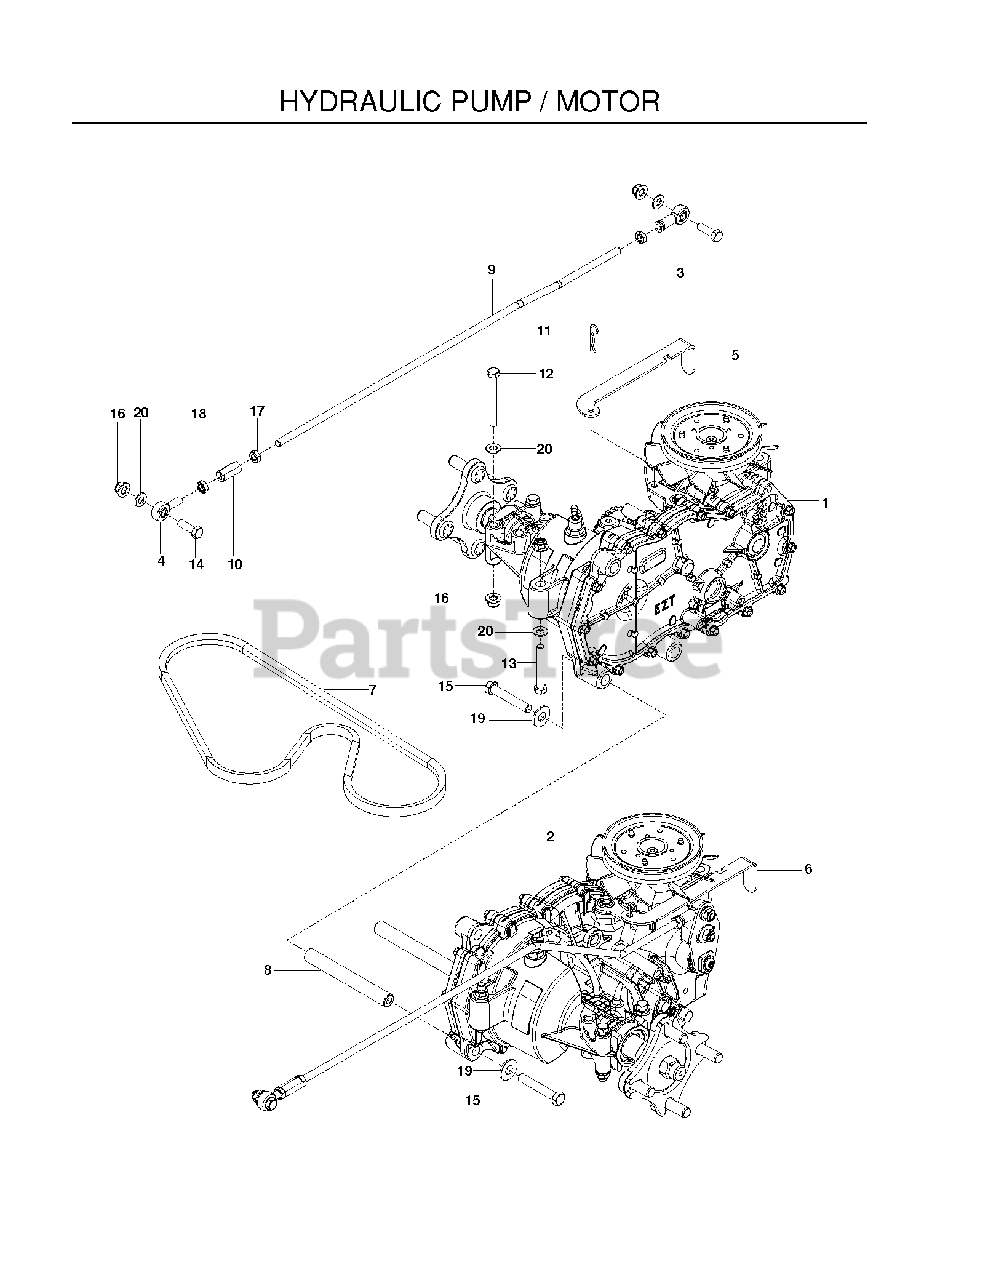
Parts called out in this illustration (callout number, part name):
1	HG_HYDRO RH
2	HG_HYDRO LH
3	RH ROD END
4	RB ROD.END.LH
5	RELEASE LEVER RH
6	RELEASE LEVER LH
7	BELT, EL 51.O4
8	SPACER, HYDRO
9	CONTROL ROD
10	ROD END COUPLER
11	HAIRPIN #2
12	HCS 5/16C X 2-3/4
14	HCS 5/16C X 1
15	HCS 3/8C X 2 1/4
16	5/16-18 NYLOC FLANGE NUT
17	NUT 5/16-24 UNF HEX JAM
18	NUT 5/16F LEFTHAND
19	RP WASHER 3/8 FLAT
20	FLAT WASHER 5/16 SAE
